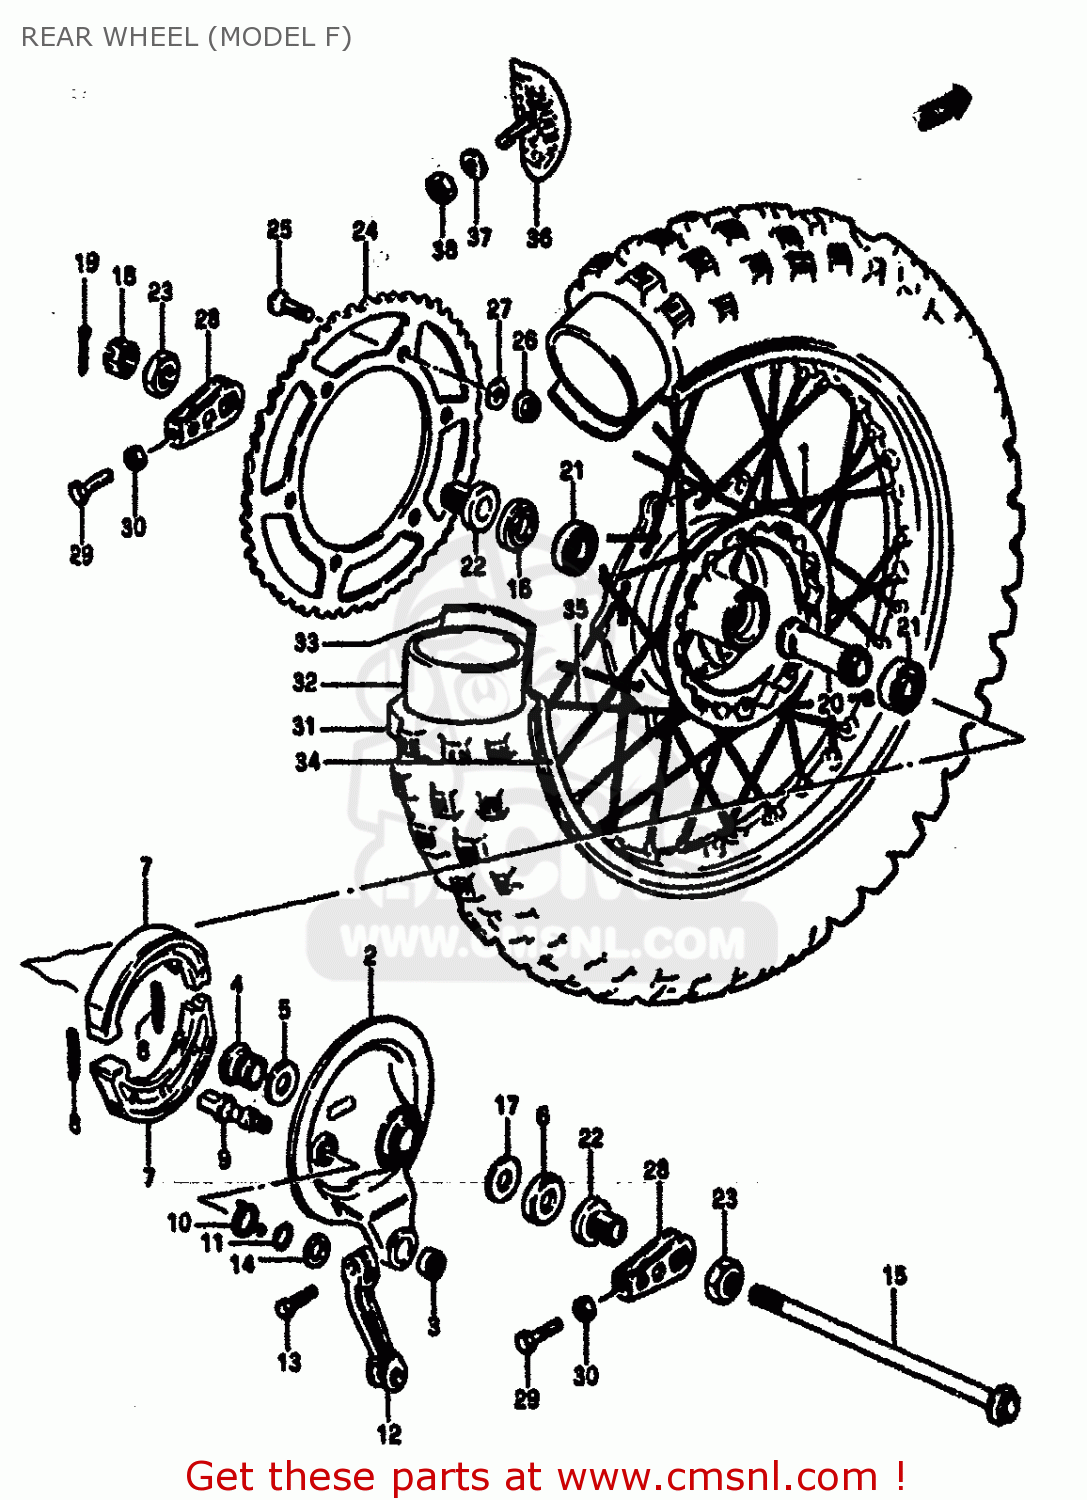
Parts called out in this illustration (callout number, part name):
1	DRUM,REAR HUB
2	PANEL SET,REAR HUB
3	BEARING
4	SPACER,RR BRAKE ANCHOR PANEL
5	SEAL,OIL(20X27X5)
6	CVR,RR BRAKE AHR PNL DUST SEAL
7	SHOE,BRAKE (MCA)
8	SPRING(L:34)
9	CAM,FR BRAKE
10	SPRING
11	O RING(D:2.5,ID:11.4)
12	LEVER,REAR BRAKE CAM
13	BOLT
14	WASHER(12.5X20X1)
15	AXLE,REAR.
16	SPACER,RR AXLE,L
17	WASHER,THRUST
18	NUT
19	COTTER PIN
20	SPACER
21	BEARING
22	SPACER,CHAIN ADJUSTER
23	NUT
24	SPROCKET,REAR
25	SCREW(8X33.5)
26	NUT
27	WASHER
28	ADJUSTER,CHAIN
29	BOLT
30	NUT
31	TIRE
32	TUBE ASSEMBLY,WHEEL,INNER
33	PROTECTOR
34	RIM,REAR WHEEL (1.85X18)
35	SPOKE SET,REAR
36	STOPPER,BEAD
37	WASHER
38	NUT
